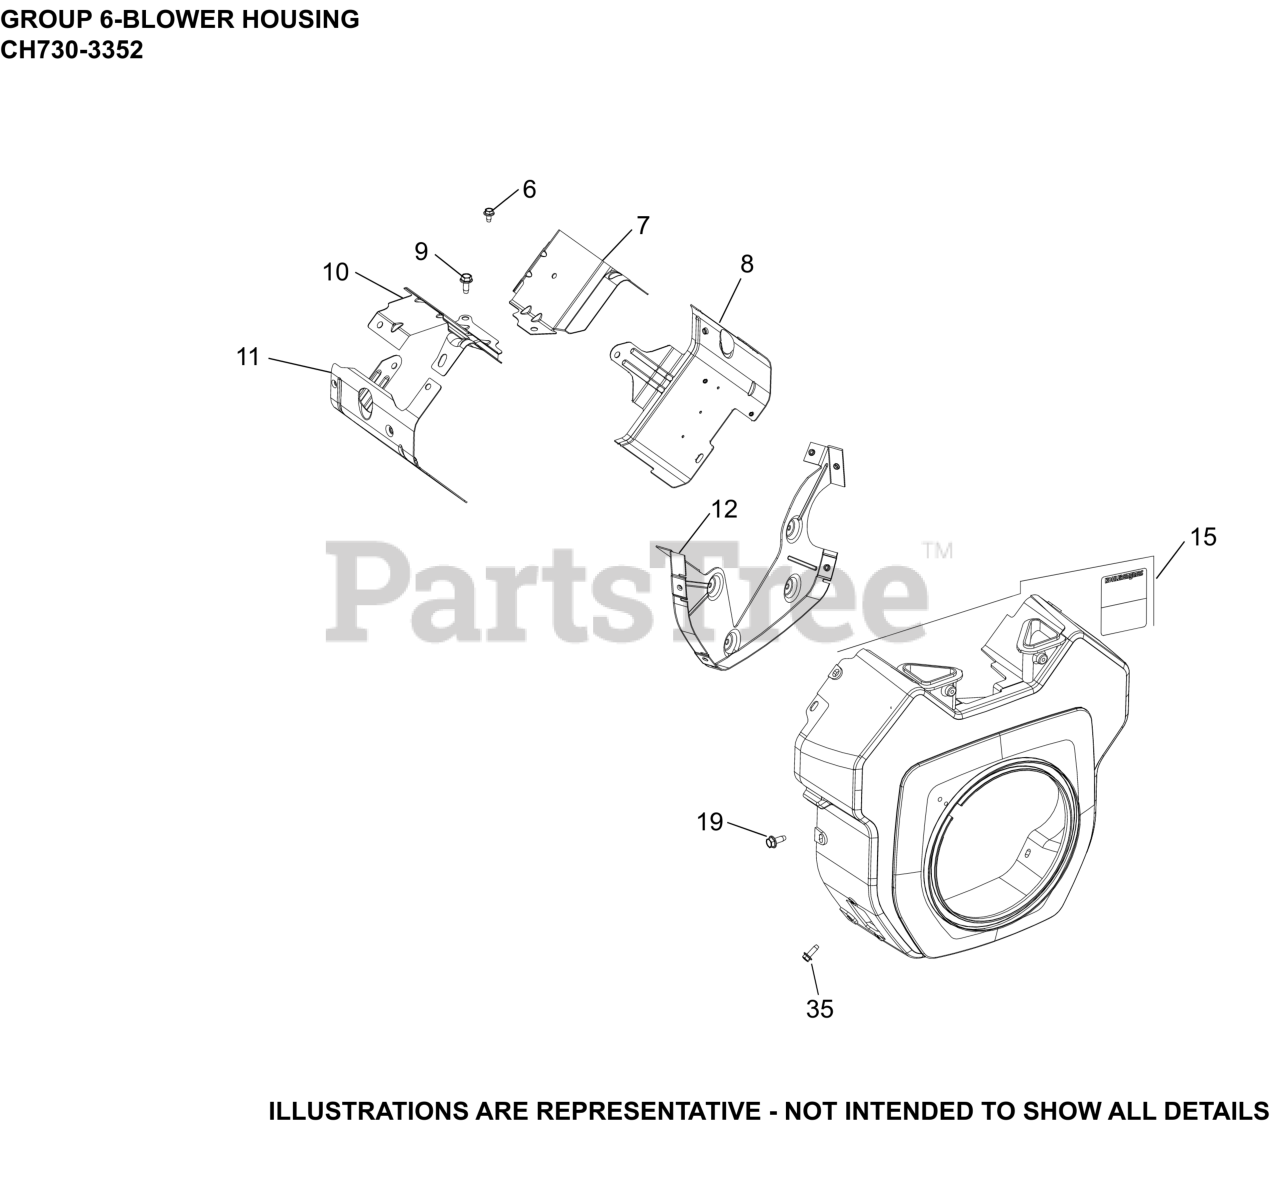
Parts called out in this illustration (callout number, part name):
6	SCREW, THREAD FORMING
7	BAFFLE, VALLEY #1 CYLINDER
8	KIT, CYL BAFFEL #1 SIDE
9	SCREW, THREAD FORMING
10	BAFFLE, VALLEY #2 CYLINDER
11	BAFFLE, LEFT BARREL
12	KIT, BACKING PLATE
15	HOUSING, BLOWER
19	SCREW, THREAD FORMING
35	SCREW, THREAD FORMING
